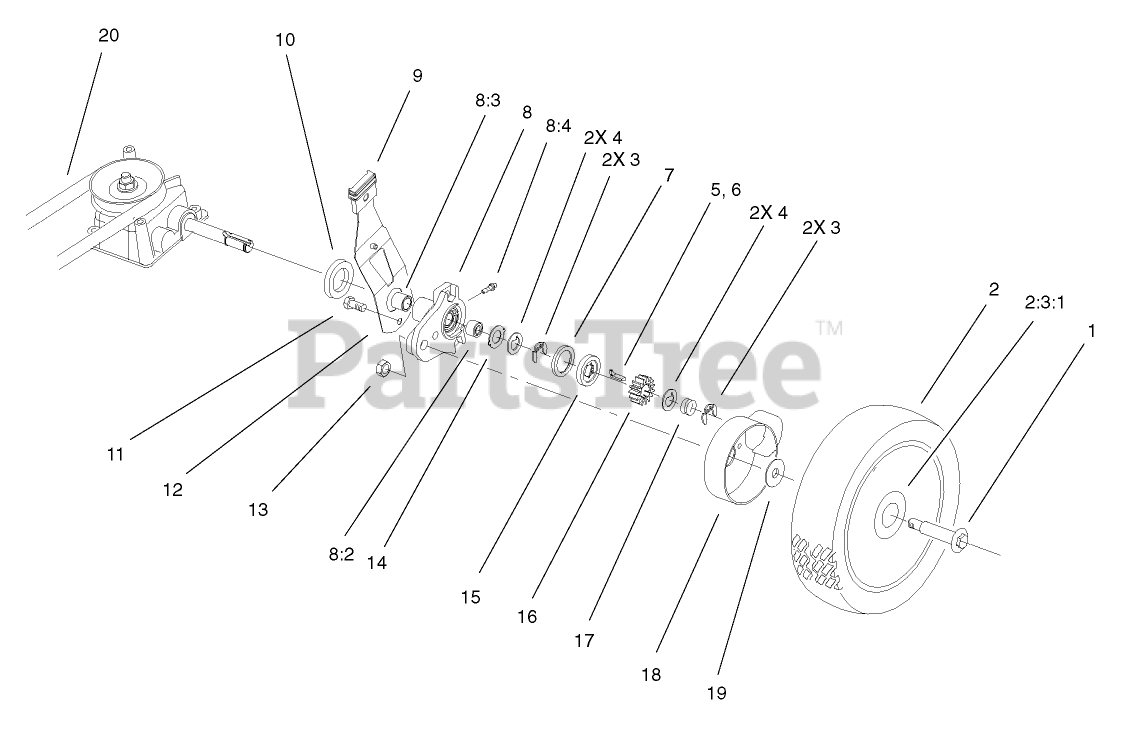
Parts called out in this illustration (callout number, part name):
1	BOLT-SHOULDER
2	WHEEL TIRE ASM (SP)
2:3:1	BUSHING
3	RING-RETAINING,CLIP
4	WASHER-THRUST, KEYED
5	KEY-ROCKING, RH
6	KEY-ROCKING, LH
7	RING-FRICTION
8	PIVOT ARM ASM
8:2	BUSHING
8:3	BUSHING
8:4	FITTING-GREASE
9	KNOB-ARM
10	CAP-END
11	SCREW-HWH
12	SPRING ARM ASM
13	LOCKNUT
14	WASHER-ARM, PIVOT
15	WASHER-CLUTCH
16	GEAR-PINION
17	SPRING-COMPRESSION
18	COVER-WHEEL
19	SPACER-COVER, WHEEL
20	BELT-V
